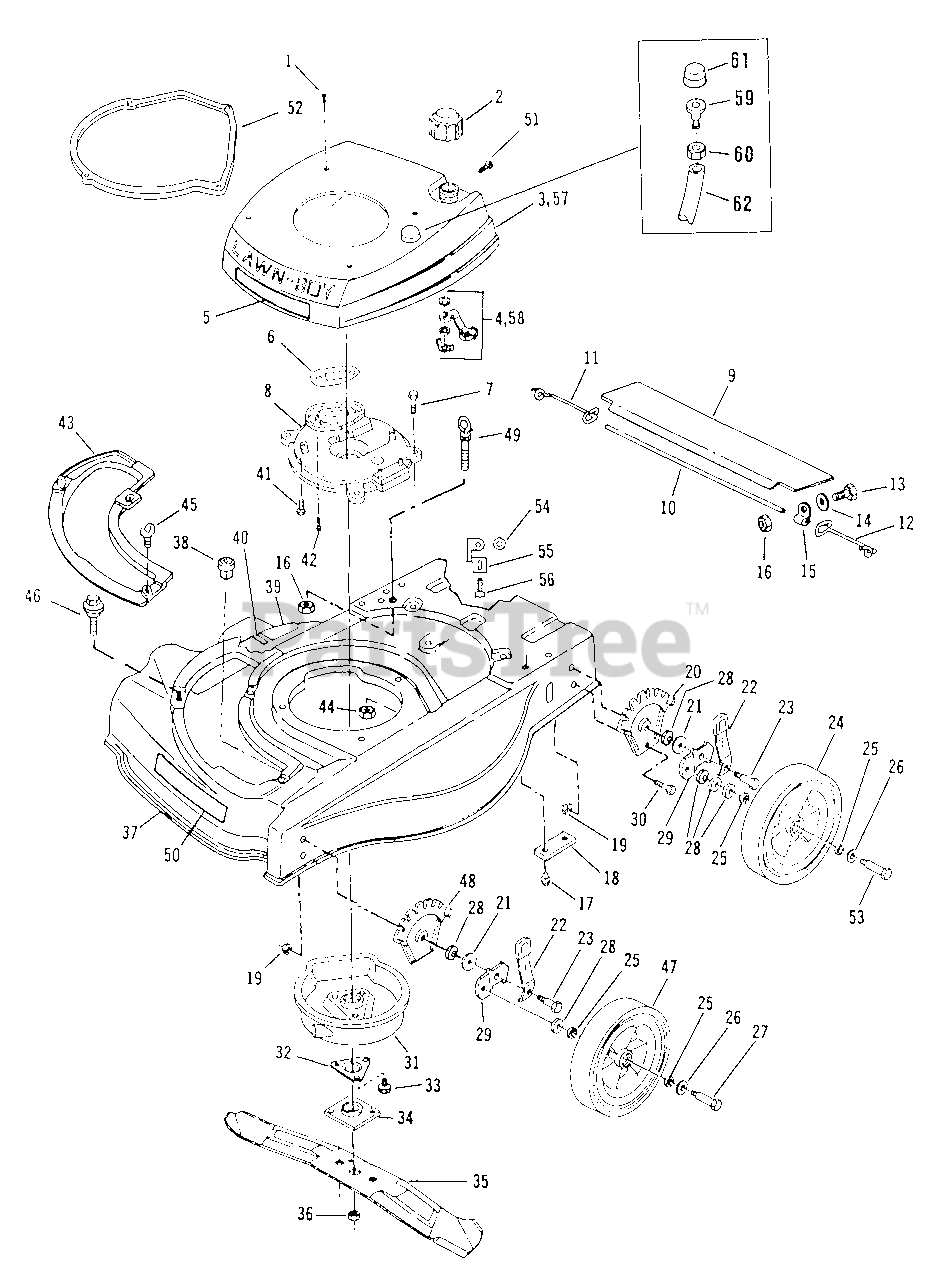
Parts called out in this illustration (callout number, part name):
1	Screw
2	Fuel Cap Assembly
5	Decal-Special
6	Gasket
7	Screw-Muffler Plate to Hsg.
8	Plate-Muffler
9	Shield-Trailing
10	Rod-Trailing Shield
11	Spring-R.H.
12	Spring-L.H.
13	Screw-Trailing Shield
14	Washer-Trailing Shield
15	Clamp-Trailing Shield
16	Nut-Trl. Shield and Eyebolt
17	Screw-Handle Bracket
18	Plate-Hdl. Brkt. to Housing
19	Nut-Hgt. Adjust and Back-up Plate
20	Plate-Height Adjust-Rear
21	Washer-Wheel Mtg. Brkt.
22	Knob and Spring Assembly
23	Bolt-Wheel Bracket to Knob and Spring Assembly
24	Wheel-Rear
25	Washer-Felt
26	Washer-Wheel Bolt Head
27	Bolt-Shoulder, Wheel-Front
28	Washer
29	Bracket-Wheel Heigth Adjust
30	Screw-Height Adjust Plate
31	Muffler Cover Assembly
32	Support-Crankshaft
33	Screw-Crankshaft Support
34	Collar and Plate Assembly
35	Blade-21"
36	Nut
37	Housing Assembly
38	Grommet
39	Decal-Blade Contact Warning
40	Decal-Discharge Area
41	Screw-Muffler Plate to Block
42	Screw-Muffler Plate to Block
43	Cover Plate
44	Nut-Muffler Plate to Housing
45	Wing Screw
46	Screw-Plate and Chute Mounting
47	Wheel-Front
48	Plate-Height Adjust-Front
49	Eyebolt
50	Decal-Headliner
51	Screw-Shroud to C.D. Bracket
52	Spacer-Shroud to Base
53	Bolt-Shoulder, Wheel-Rear
54	Nut-Baffle Bracket
55	Bracket-Baffle
56	Screw-Baffle Bracket
57	Shroud-Tank & Valve Assembly
58	Fuel Valve Assembly
59	Base-Primer
60	Locknut
61	Primer Bulb
62	Tubing-Primer
